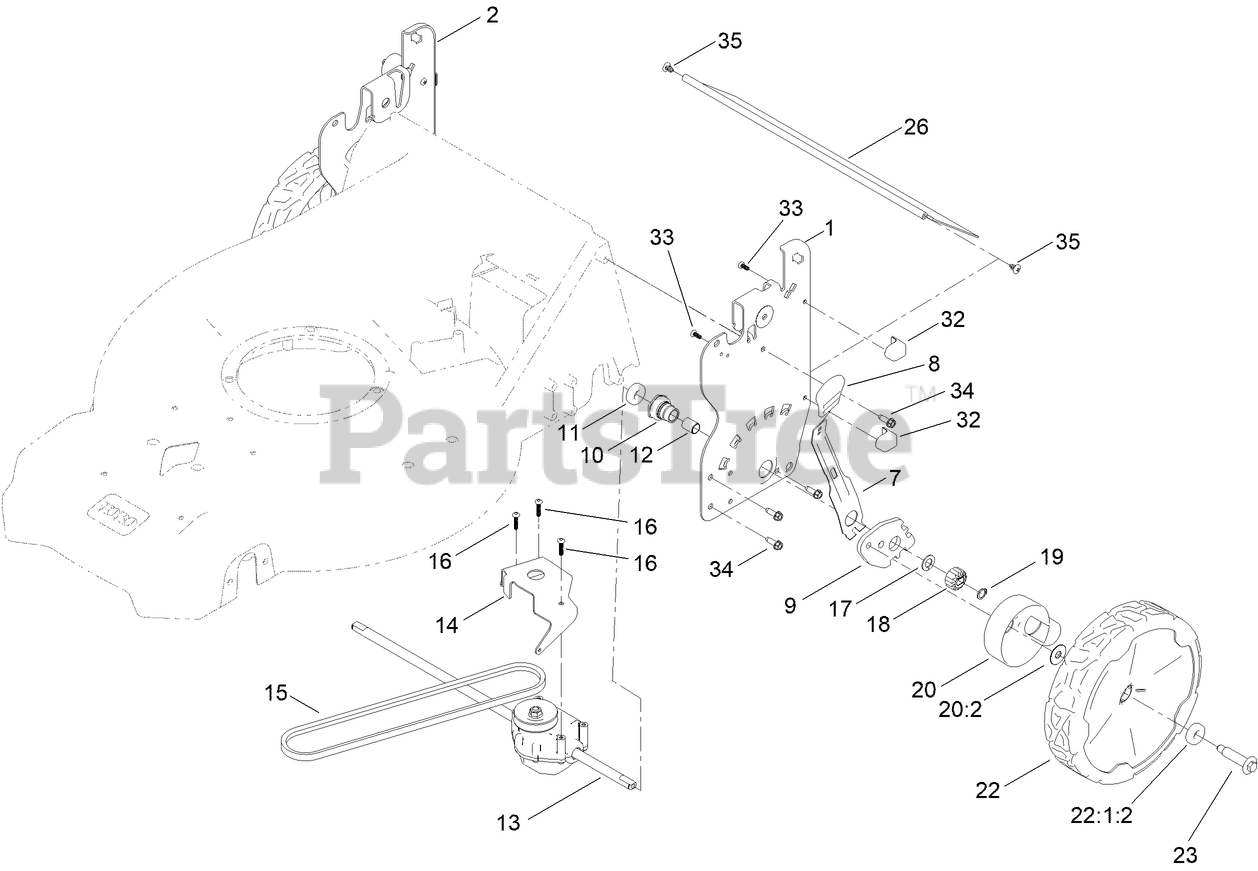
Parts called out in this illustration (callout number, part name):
1	PLATE-HOC, LH
2	PLATE-HOC, RH (2 HOLE)
7	ARM-SPRING
8	KNOB-HOC
9	ARM-PIVOT, REAR
10	RETAINER-BUSHING, HOC
11	BEARING-WHEEL
12	BUSHING-SLEEVE
13	TRANSMISSION-RWD, 5.25:1
14	BRACKET-TRANS, RWD HI
15	BELT-V
16	SCREW-PLASTITE
17	WASHER-THRUST
18	GEAR-PINION, 15T
19	RING-RETAINING
20	ASM-COVER, GEAR
20:2	WASHER-STEPPED
22	ASM-9.65" WHEEL, GEARED
22:1:2	BEARING-WHEEL
23	BOLT-SHOULDER
26	SHIELD-TRAILING
32	PAD-SMART STOW
33	SCREW-PPH
34	SCREW-HWHTF
35	SCREW-THD
